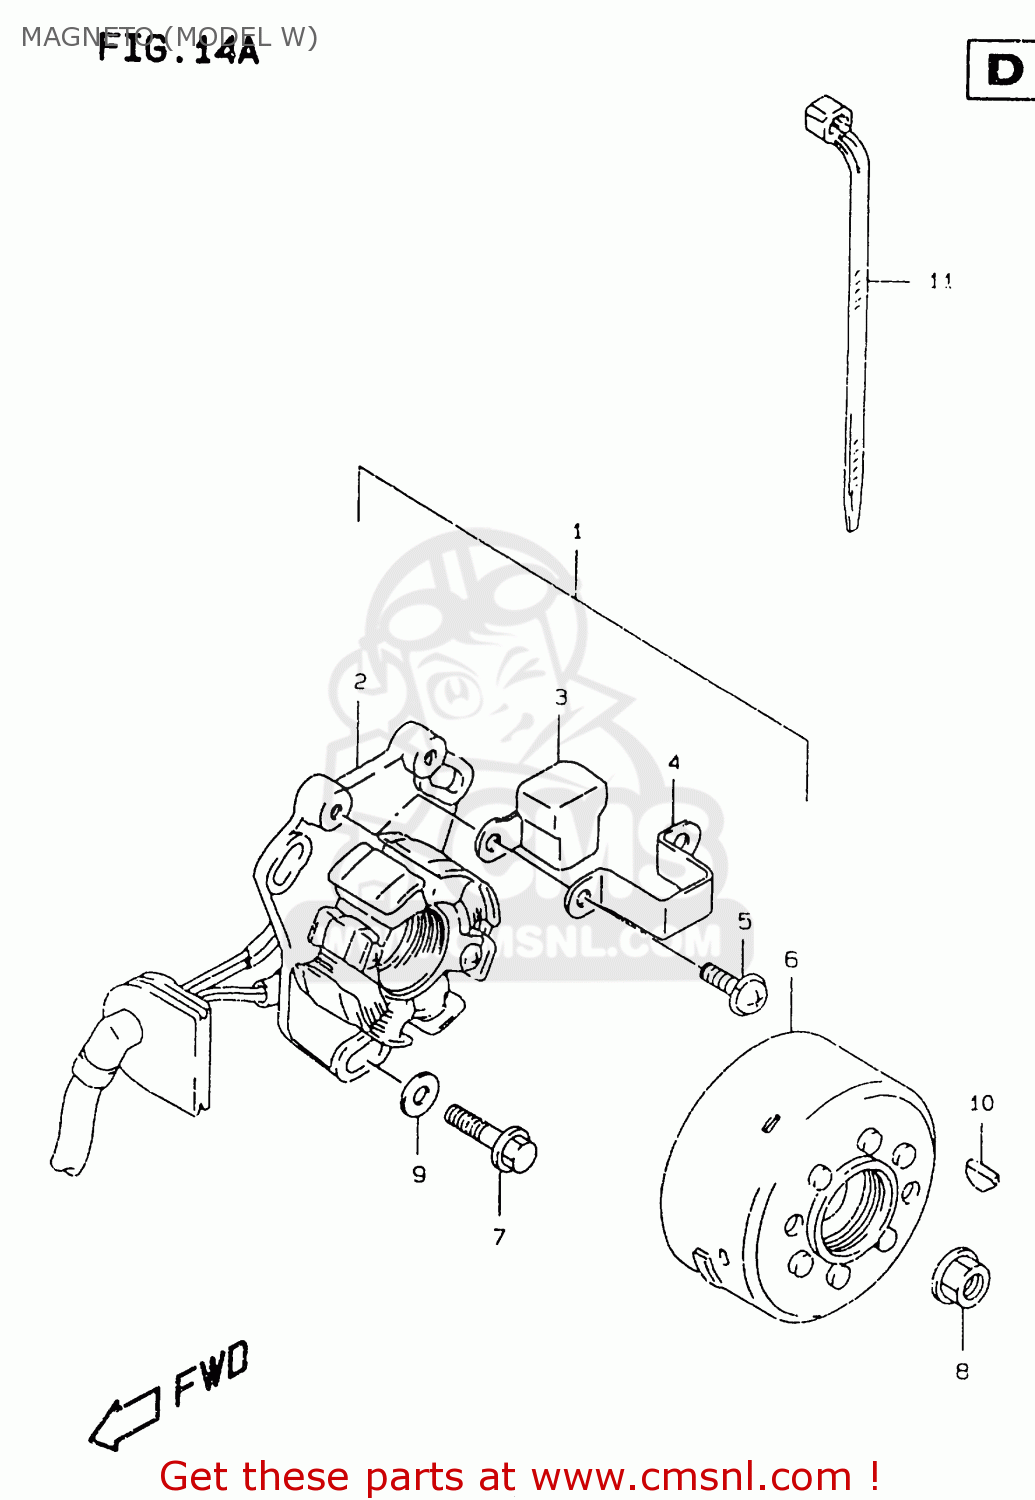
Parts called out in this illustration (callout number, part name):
1	MAGNETO ASSEMBLY
2	STATOR ASSEMBLY
3	COIL,PULSER
4	HOLDER,PICK UP COIL
5	SCREW
6	ROTOR ASSY
7	SCREW
8	NUT
9	WASHER
10	KEY
11	CLAMP(L:235)
